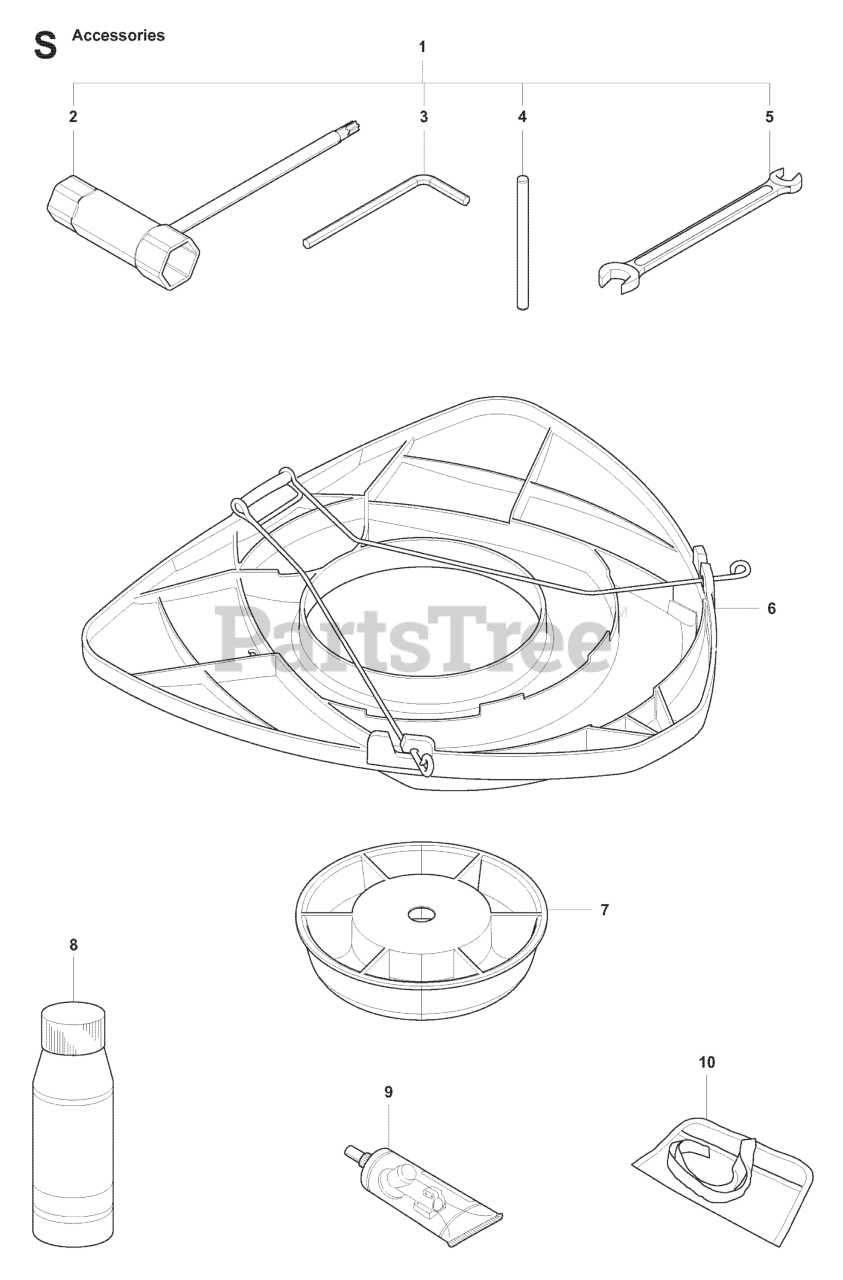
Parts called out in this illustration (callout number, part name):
6	TRANSPORT GUARD
7	SUPPORT CUP
8	Air Filter Oil 1l.
9	BEVEL GEAR GREASE
